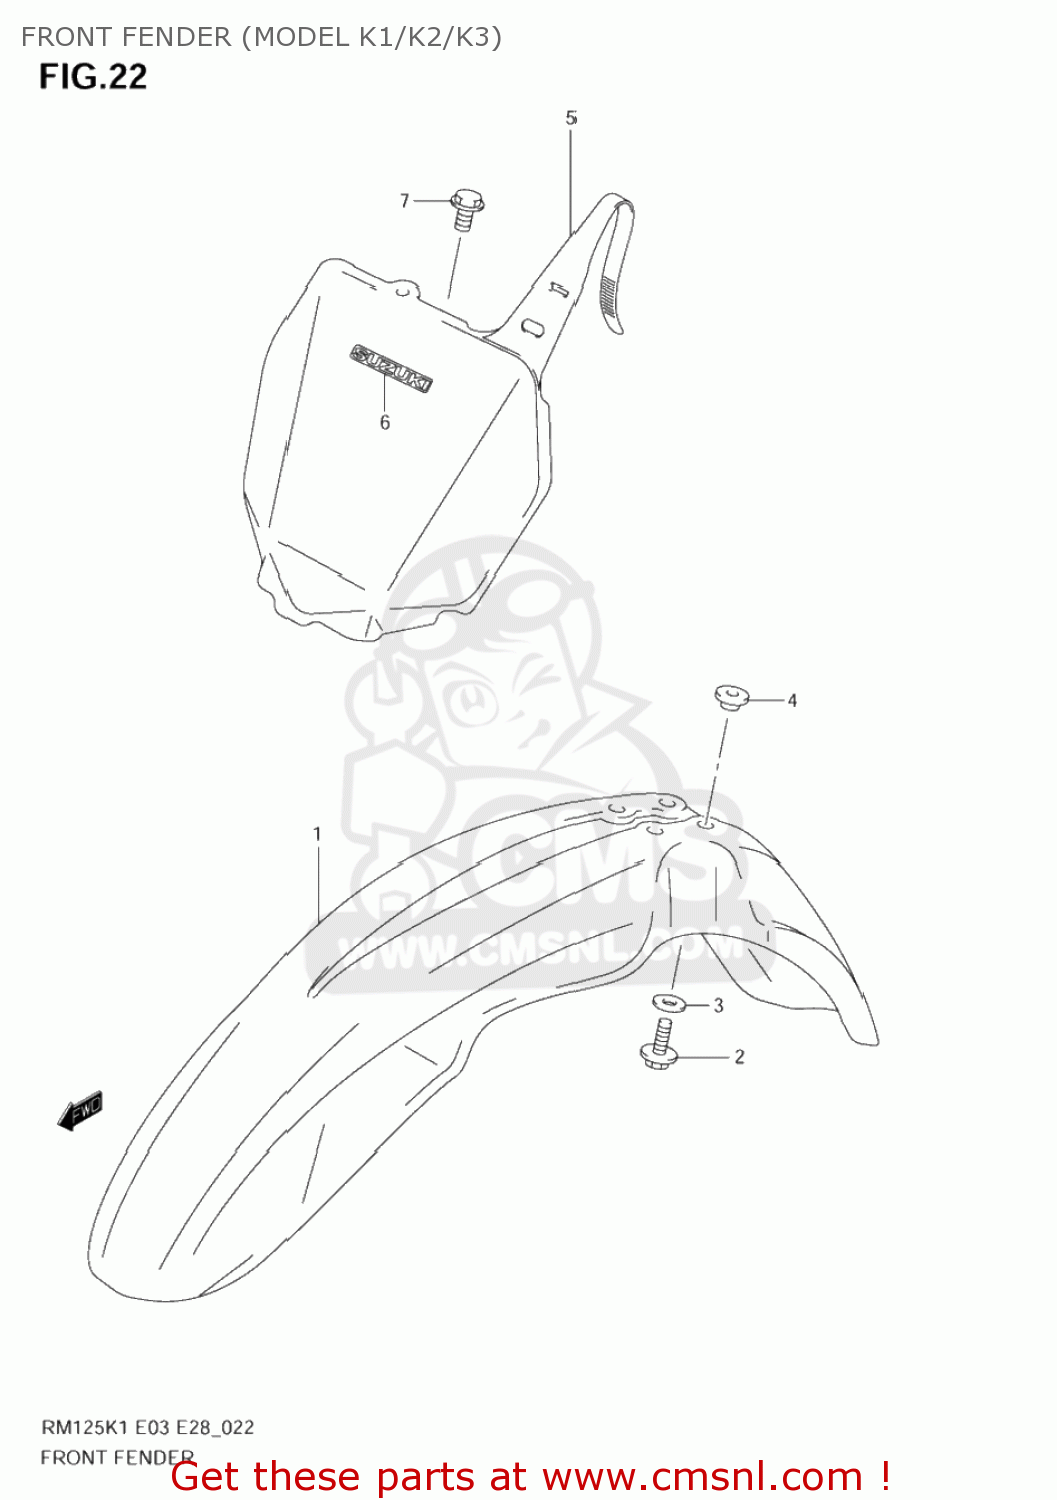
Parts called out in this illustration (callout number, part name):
1	FENDER,FR
2	BOLT
3	WASHER(6.5X28X1.6)
4	WASHER
5	PLATE,NUMBER F
6	EMBLEM,SUZUKI
7	BOLT
